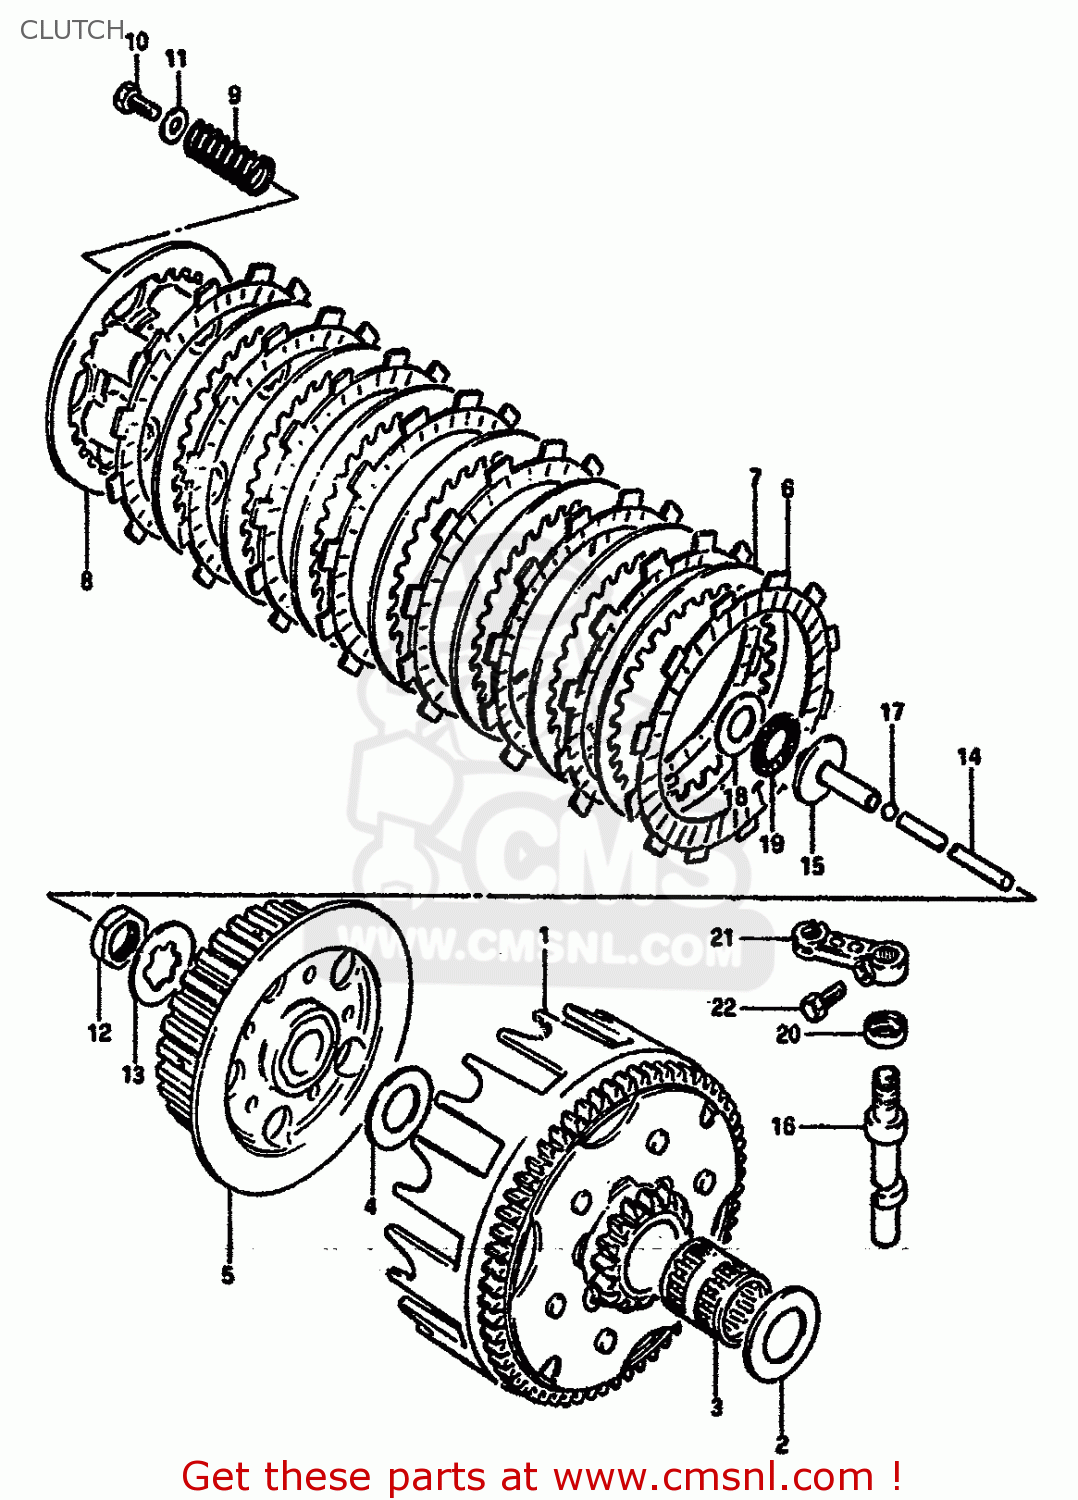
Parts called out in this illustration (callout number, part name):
1	GEAR ASSEMBLY,PRIMARY DRIVE
2	WASHER,THRUST
3	BEARING(20X25X26)
4	WASHER
5	HUB,CLUTCH SLEEVE
6	PLATE,CLUTCH DRIVE
7	PLATE,CLUTCH DRIVEN (NAS)
8	PLATE,CLUTCH PRESSURE
9	SPRING
10	BOLT(5X16)
11	WASHER (5.5X16X1.2)
12	NUT
13	WASHER,LOCK
14	ROD,CLUTCH PUSH
15	PIECE,CLUTCH PUSH
16	SHAFT,CLUTCH RELEASE C
17	BALL
18	WASHER
19	BEARING(15X28X2)
20	OIL SEAL
21	ARM,CLUTCH RELEASE
22	BOLT, UPPER
